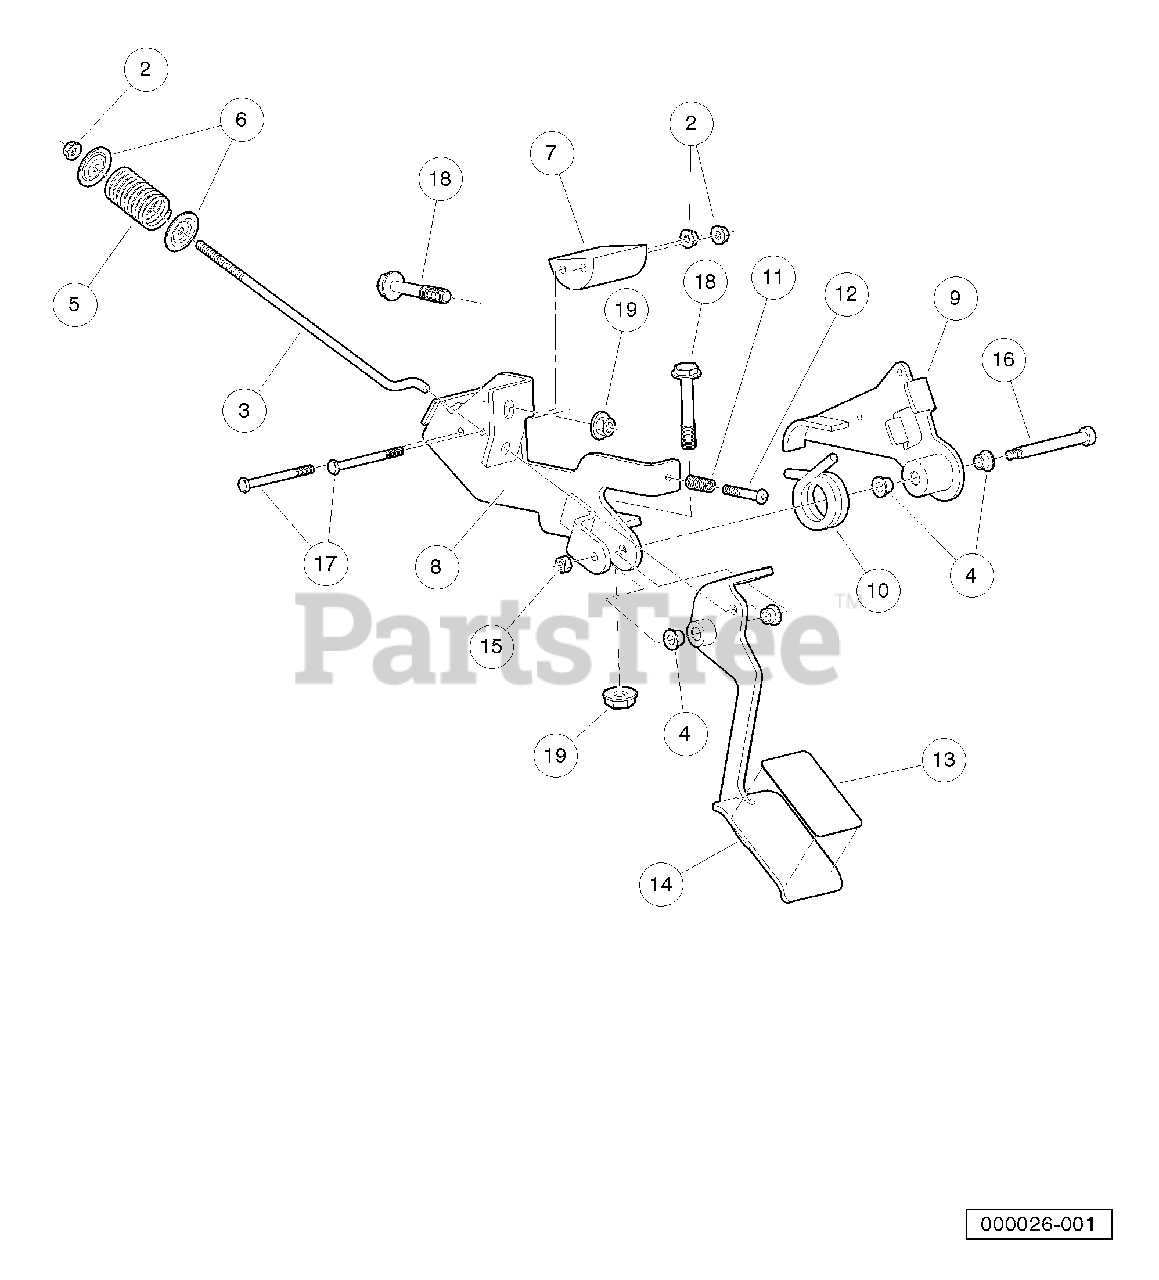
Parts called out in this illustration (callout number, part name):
1	Asm, Pedal, Accelerator
2	Nut-m6x1.0 Flng All Mtl Lock
3	Pullrod, Spring, Compression
4	Bushing, Greaseless
5	Spring, Comp, Pedal, Pullrod
7	Guide, Cable, Accelerator
8	Weldment, Bracket, Pedal
9	Weldment, Lever, Motion, Lost
10	Spring, Torsion
11	Spring, Stop, Pedal
12	Bolt, Stop, Pedal
13	Pad, Grip Tape, Accelerator
14	Weldment, Pedal, Accelerator
15	Nut M6x1 Mech Def Center
16	Bolt, Shoulder, M8 X 70, Hc
17	Bolt, M6 X 1 X 70
18	Bolt Flanged Head, M8 X 1.25 X 65
19	Lock Nut, Flg M8 X 1.25 Nylon
